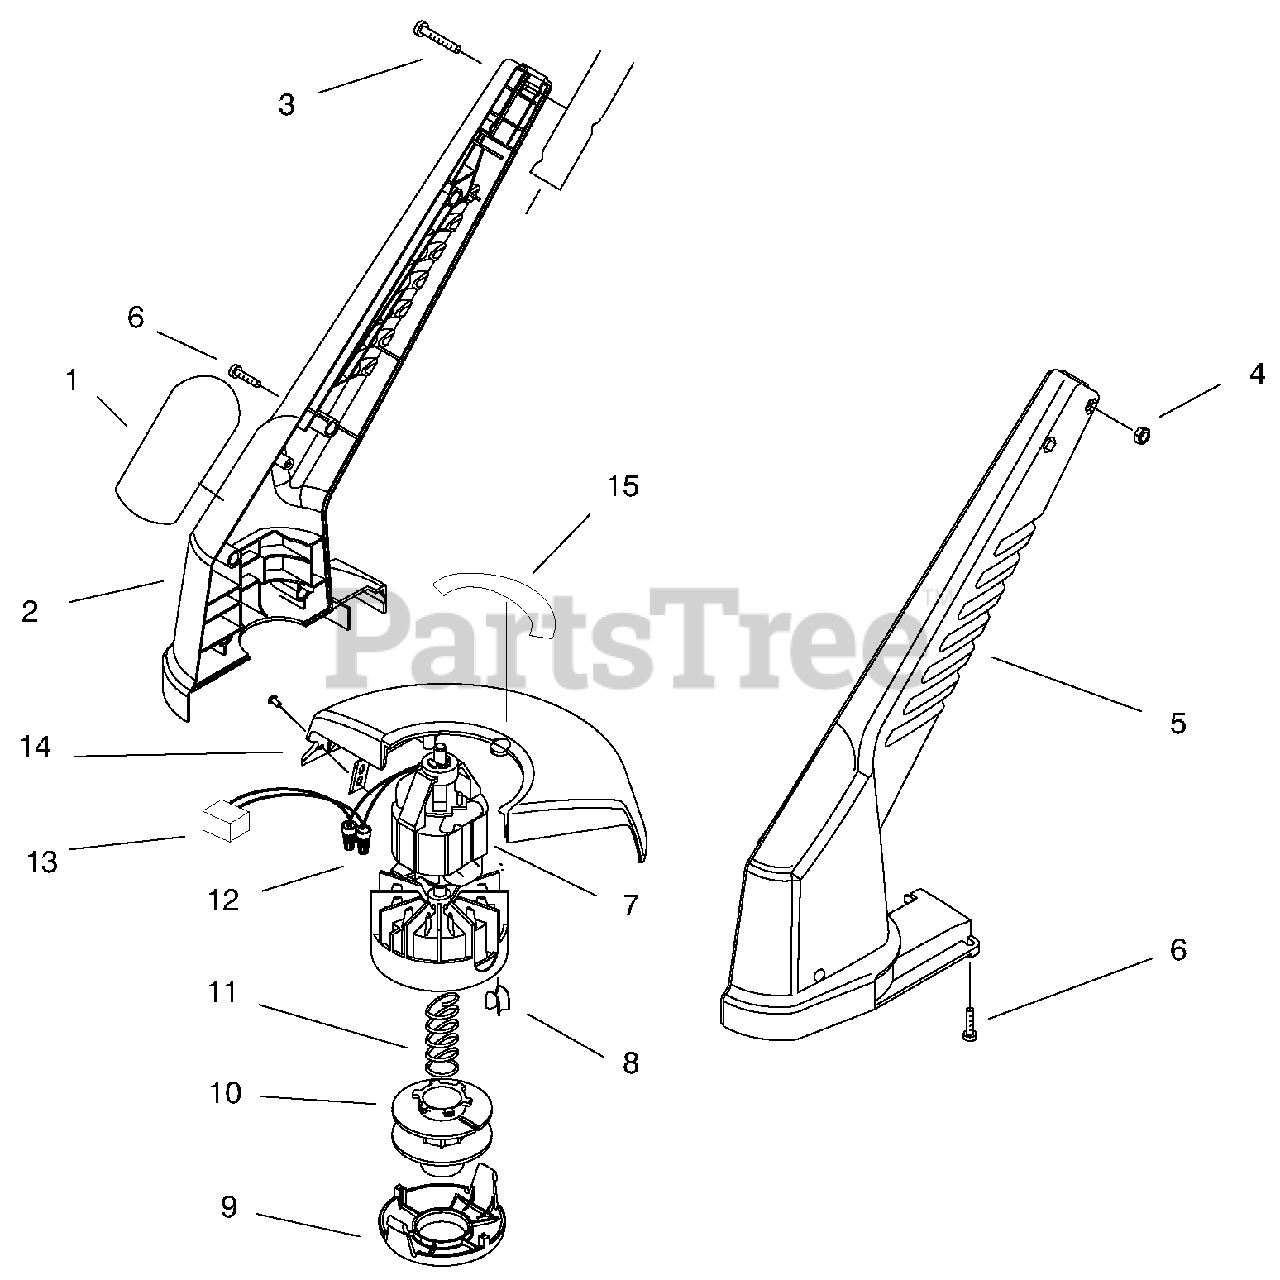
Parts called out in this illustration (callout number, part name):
1	Decal-35CM Trimmer
2	Housing R.H.
3	Screw-Pan Hd.
5	Housing L.H.
6	Screw-Pan Hd.
7	Motor Assembly-Trimmer (Incl. Ref. #8)
12	Connector-Wire Nut
14	Shield Assembly
15	Decal-Shield
